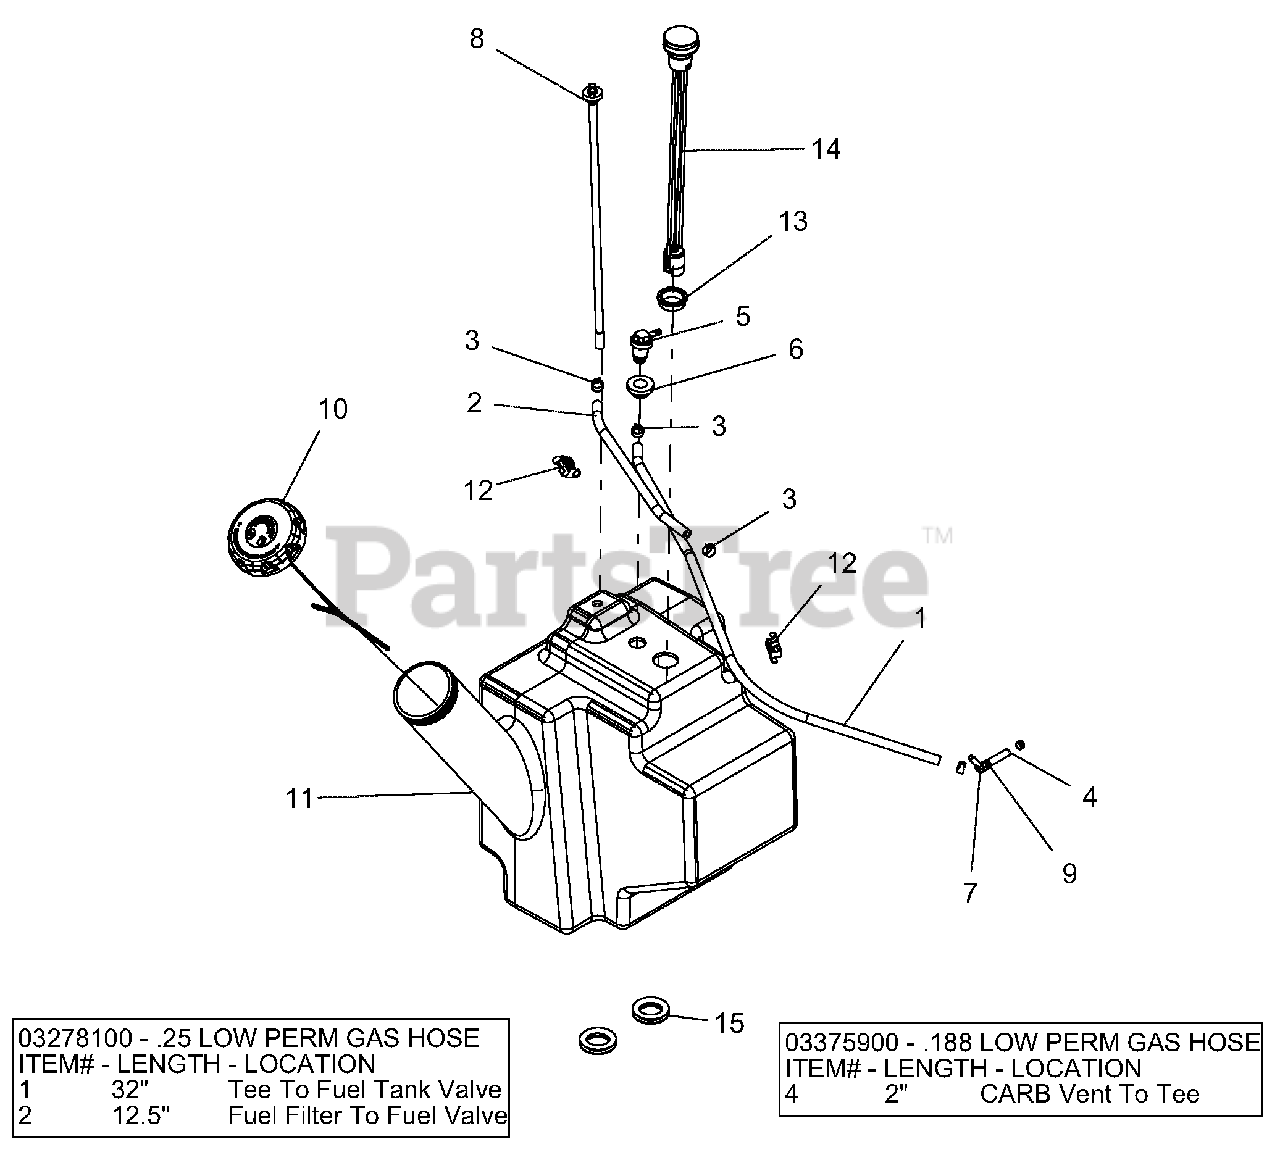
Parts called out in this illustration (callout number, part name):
1	.25 LOW PERM GAS HOSE
2	.25 LOW PERM GAS HOSE
3	CLAMP, FUEL LINE
4	HOSE, .188 LOW-PERM BULK GAS
5	VALVE, COMBINATION
6	GROMMET, REMOTE VENT NITRILE
7	FITTING-3/16X1/4 90DEGREE VAC
8	ASM, LARGE TANK FUEL PICK-UP
9	CLAMP - HOSE, SPRING .188
10	CAP, FUEL VENT-IN AUTOLOCK
11	TANK, FUEL COMPACT PROSTANCE
12	CLIP, T, .38-.50
13	GROMMET, FUEL GAUGE
14	GAGE, REMOTE FUEL SEALED 15"
15	GROMMET, 1.25"
